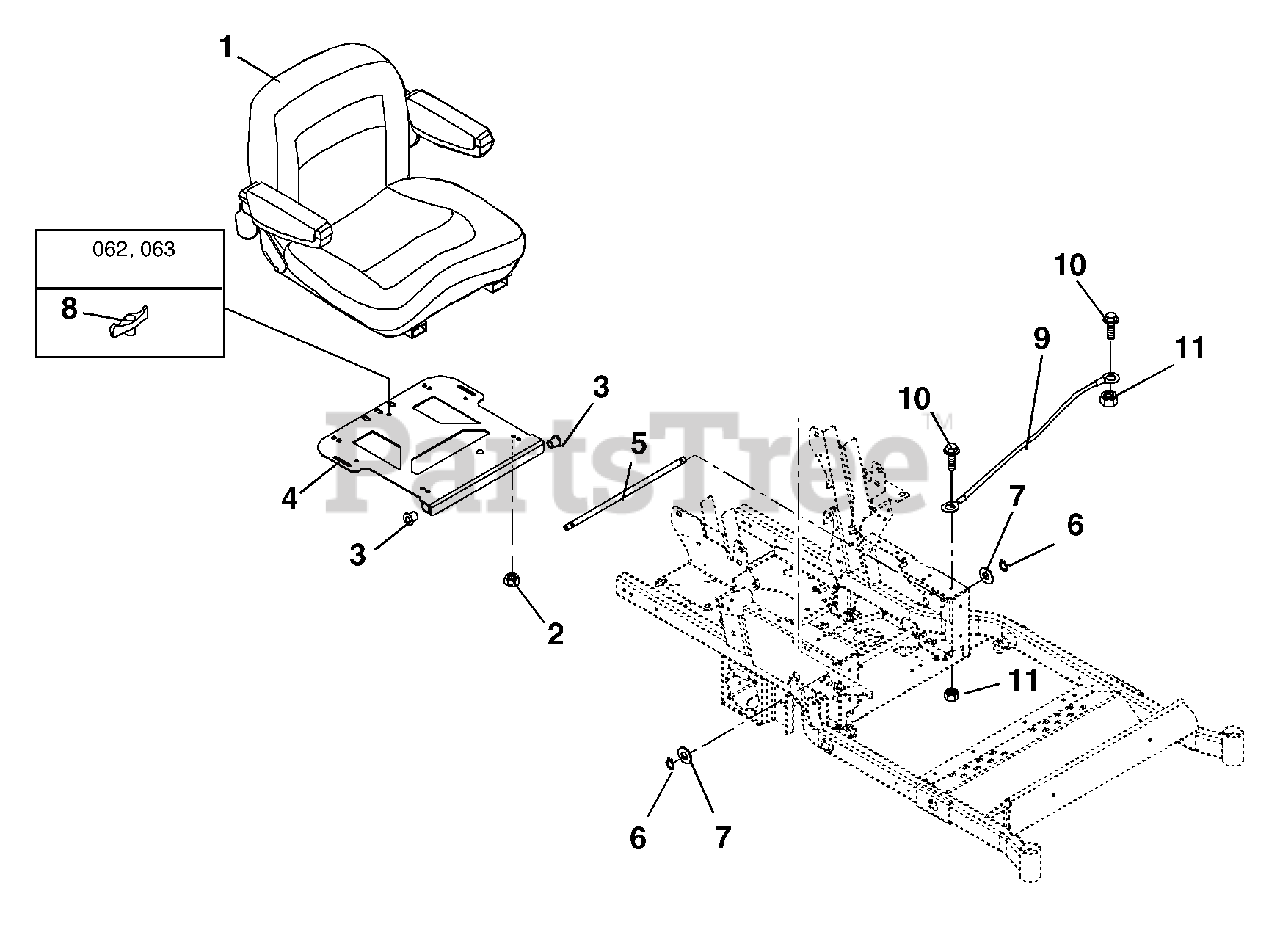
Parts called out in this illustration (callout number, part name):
1	SEAT, MILSCO XB180 - ZOOM
2	@NUT-LK-TOP-FLG .31-18 YWZC
3	BSHG-FLG .515X.750X.745X1.00NY
4	WMT, SEAT PIVOT MOUNT
5	ROD, SEAT FRAME PIVOT
6	RG-RTNG-EXT .500X.050 (SNAP)
7	@WSHR-FL-STL.531X1.06X.095YWZC
8	KNOB - WING .312-18 UNC
9	CBL,HOOD
10	@BLT-HEX .25-20X.75 GR5 YWZC
11	@NUT-LK-TOP-FLG .25-20 YWZC
